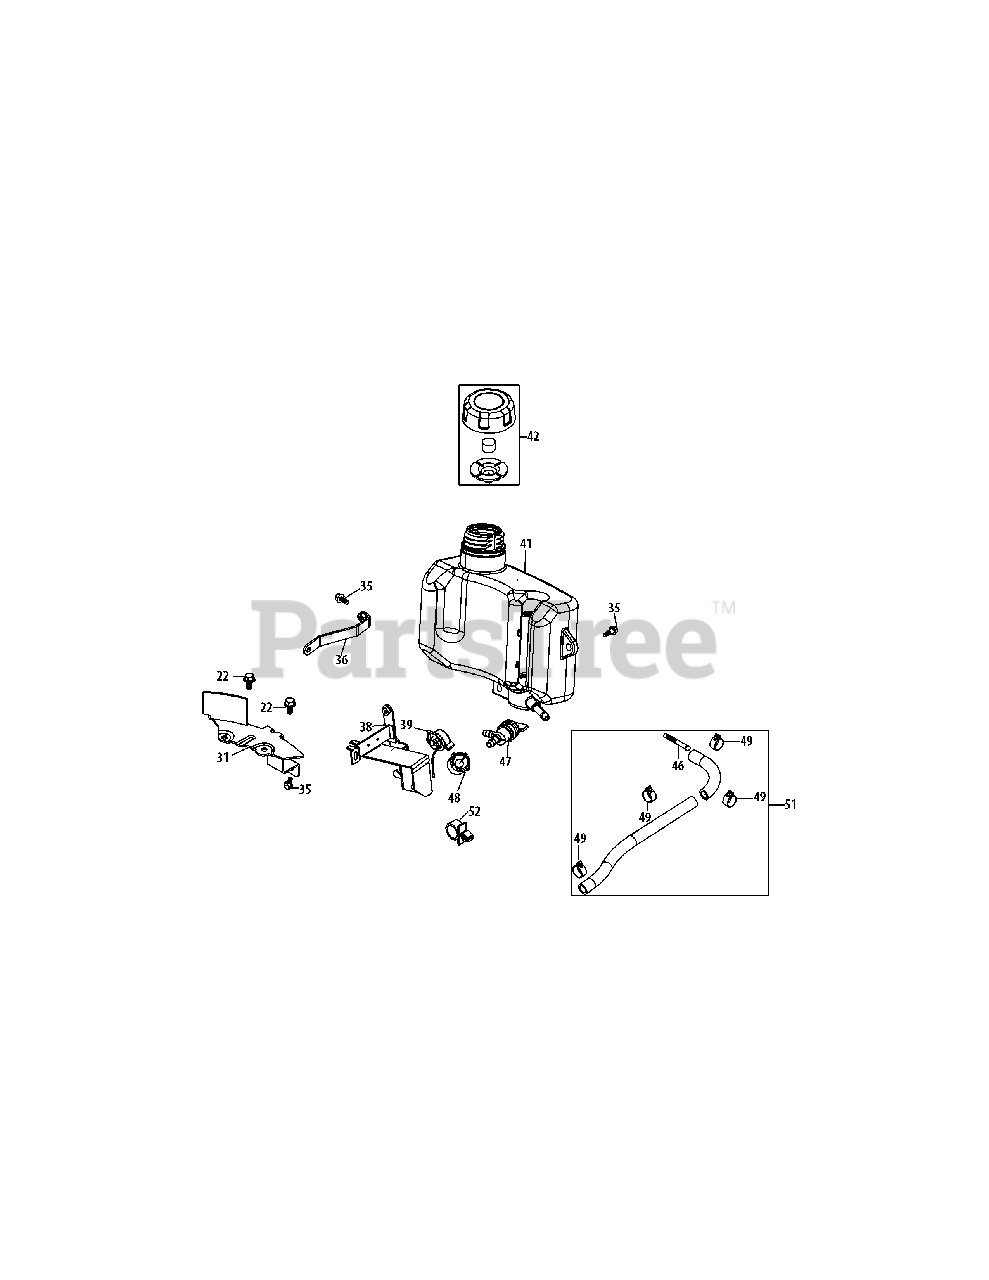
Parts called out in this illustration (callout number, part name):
22	Bolt M6×14
31	Fuel Tank Bottom Bracket
35	Fuel Tank Bolt
36	Fuel Tanksupport Bracket
38	Control/Tank Bracket
39	Ignition Key Switch
41	Fuel Tank - Clear White
42	Fuel Cap Assembly
46	Fuel Filter
47	Fuel Shut Off Valve
48	Fuel Shut Off Support Clip
49	Fuel Hose Clamp
51	Fuel Line Kit
52	Plastic Support Clamp
